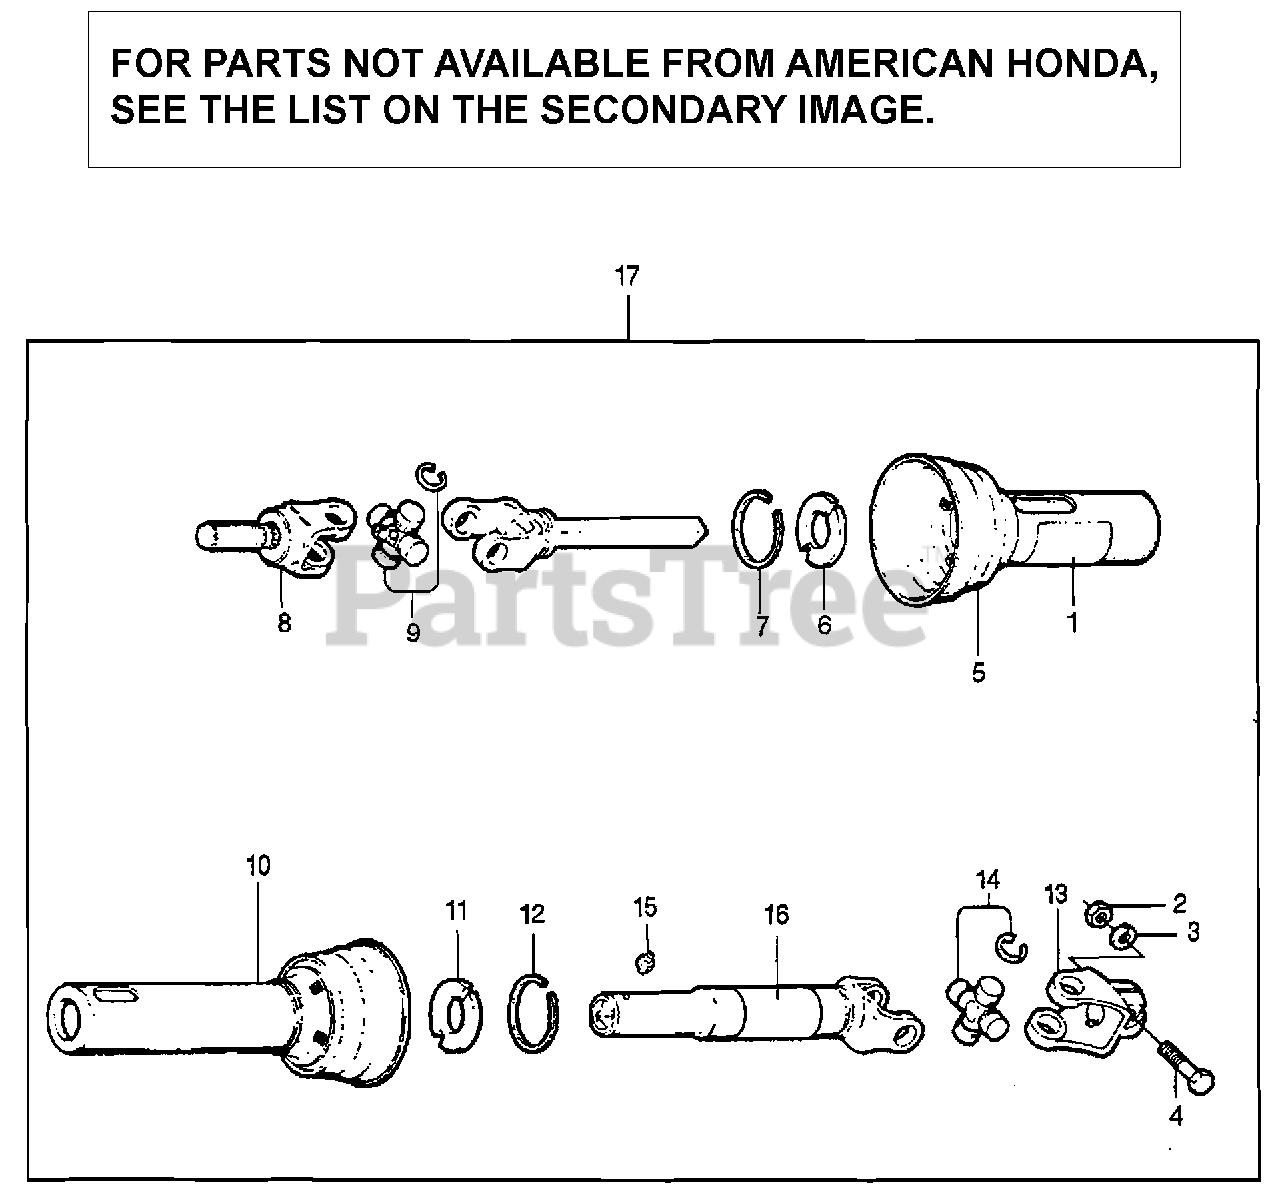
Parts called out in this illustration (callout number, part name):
3	SCREW, CAP (3/8") (16 UNC) (NOT AVAILABLE)
5	FRAME ASSY. (NOT AVAILABLE)
6	BEARING, NYLON
7	RETAINER, BEARING
8	YOKE, TRACTOR
9	CROSS & BEARING KIT
10	SHIELD ASSY. (INNER)
11	BEARING, NYLON
12	RETAINER, BEARING (NOT AVAILABLE)
13	YOKE, IMPLEMENT
14	CROSS & BEARING KIT
15	FITTING, GREASE (NOT AVAILABLE)
17	DRIVESHAFT ASSY. (NOT AVAILABLE)
